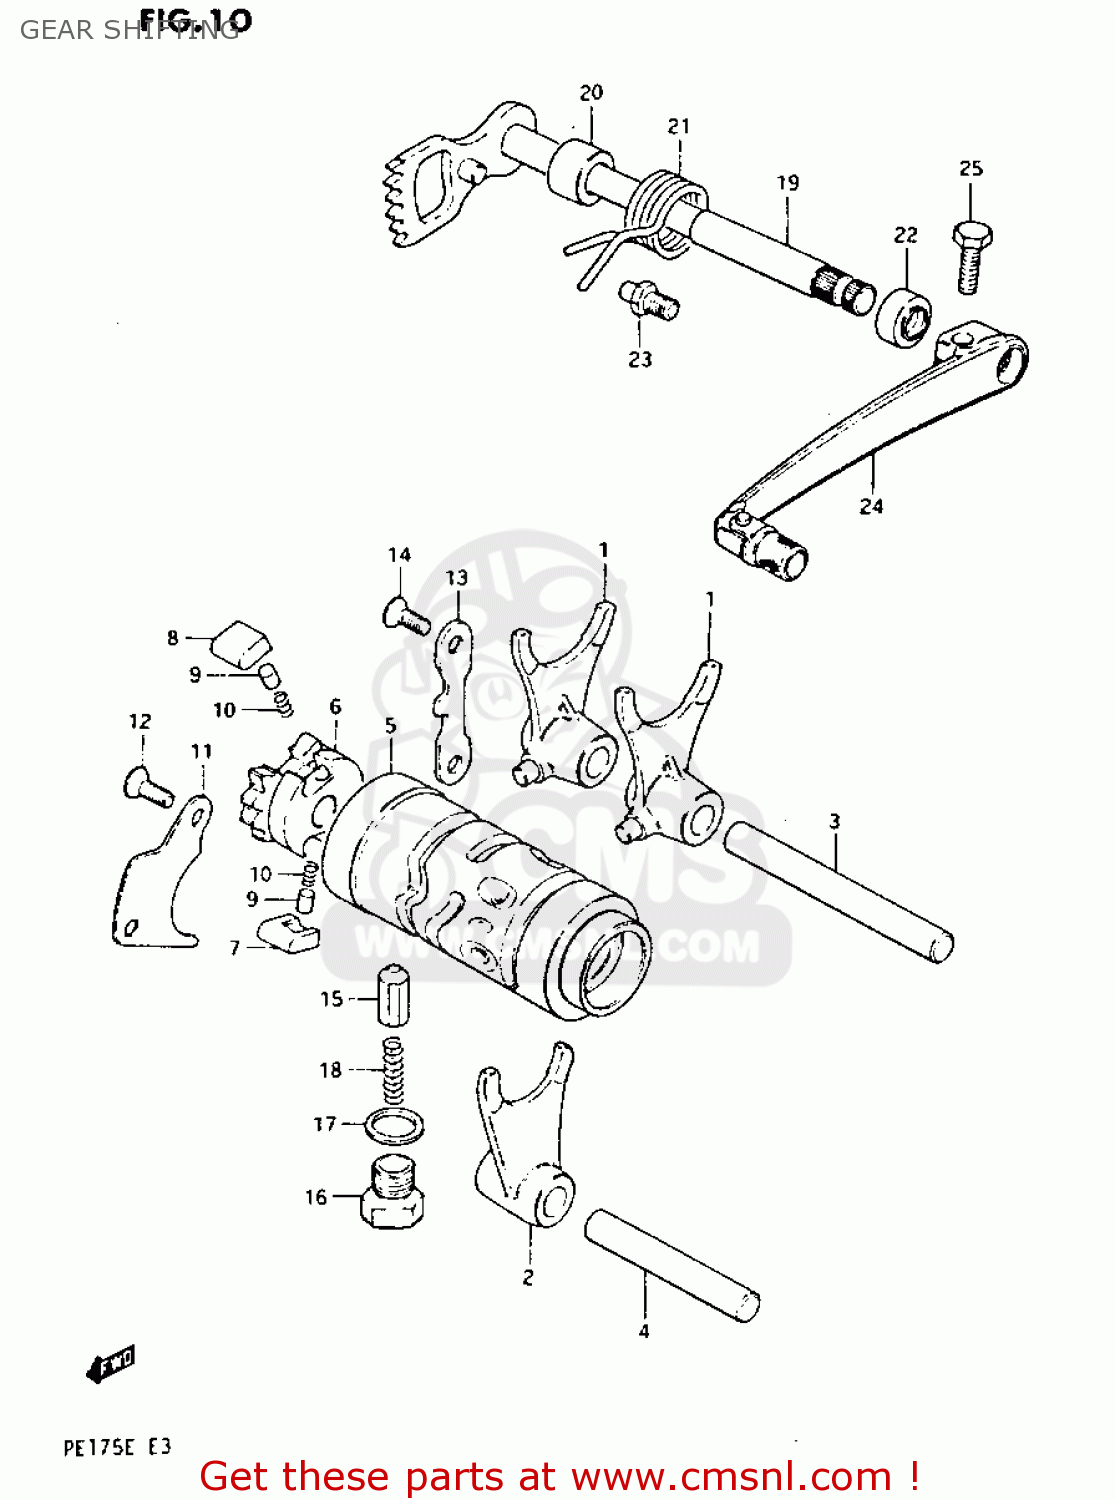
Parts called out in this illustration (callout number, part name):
1	FORK,GEAR SHIFT NO.1
2	FORK,GEAR SHIFT NO.2
3	SHAFT,GEAR SHIFT FORK
4	SHAFT,GEAR SHIFT FORK
5	CAM,GEAR SHIFT
6	GEAR,GEARSHIFT CAM DRIVE
7	PAWL,GEAR SHIFT NO.1
8	PAWL,GEAR SHIFT NO.2
9	PIN(5X8)
10	SPRING
11	LIFTER,GEAR SHIFT PAWL
12	SCREW
13	STOPPER,GEAR SHIFT POLE
14	SCREW
15	STOPPER,GEAR SHIFTING
16	HOUSING,GEAR SHIFT CAM STOPPER
17	GASKET(14X19.2X2) (NAS)
18	SPRING
19	SHAFT,GEAR SHIFT
20	SPACER(12X20X15.3)
21	SPRING
22	OIL SEAL
23	STOPPER,GEAR SHIFT CAM
24	LEVER,GEAR SHIFT
25	BOLT
